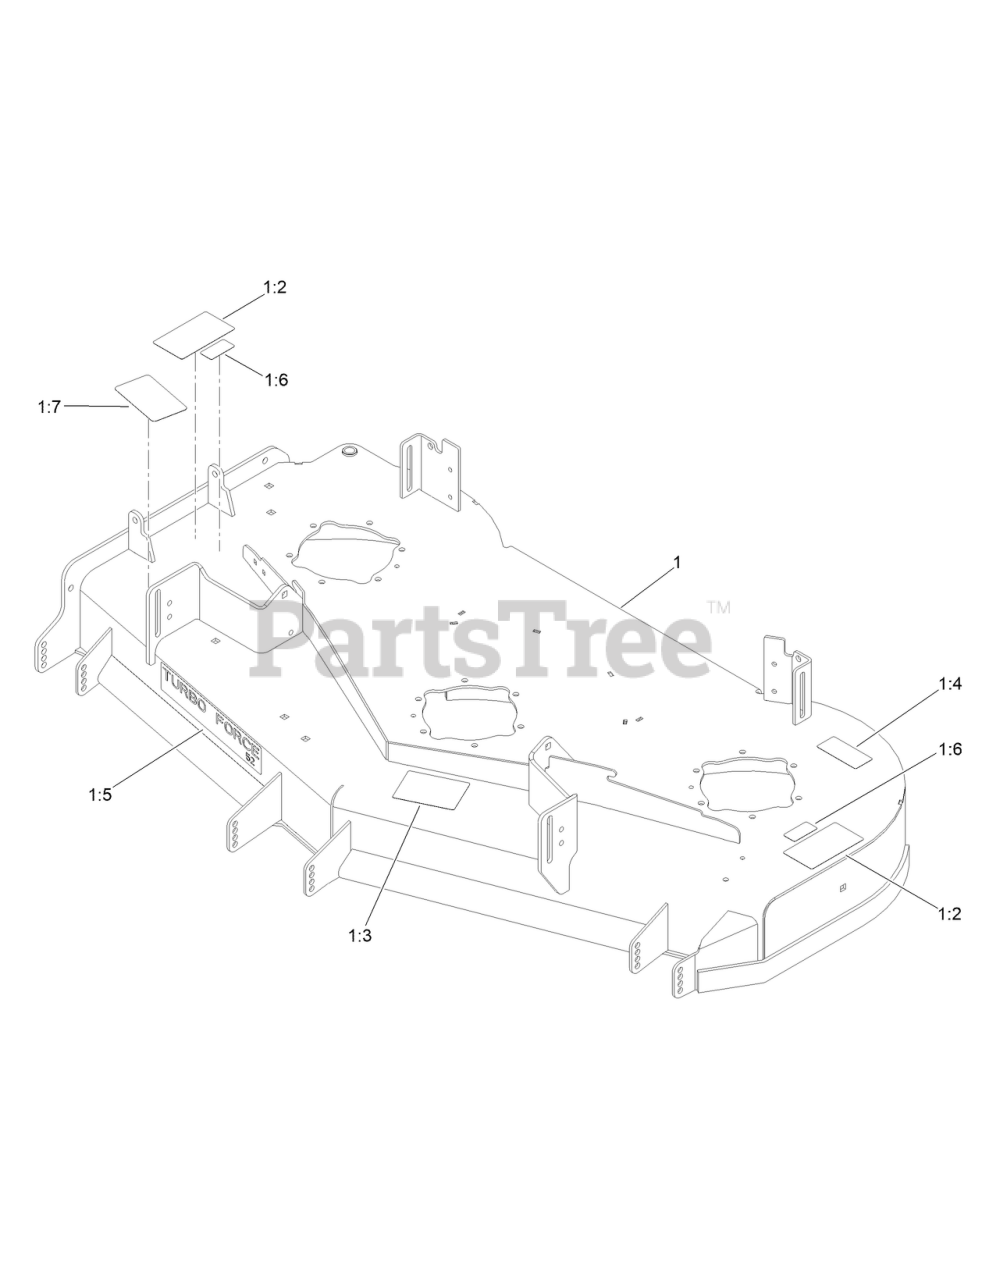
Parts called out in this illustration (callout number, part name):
1:2	DECAL-DANGER
1:3	DECAL-SCALP, ANTI
1:4	DECAL-DANGER
1:6	DECAL-NO SPRAY
1:7	DECAL-ADJUSTABLE BAFFLE
